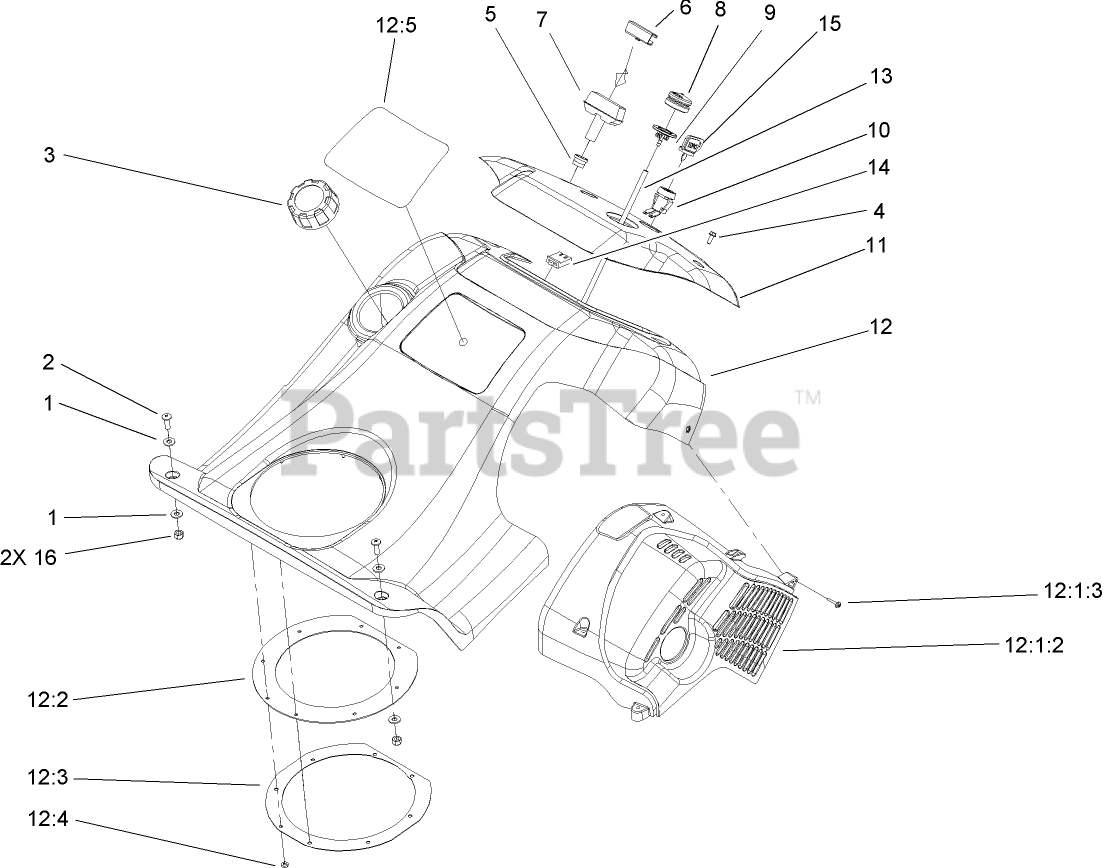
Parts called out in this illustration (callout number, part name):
1	WASHER-FLAT
2	SCREW-PPH
3	GAS CAP ASM
4	SCREW-HWH
5	GUIDE-ROPE, STARTER
6	CLIP-STARTER
8	BULB-PRIMER
9	BODY-PRIMER
10	SWITCH
12:1:2	SHIELD-HEAT
12:1:3	SCREW-PPH
12:2	SEAL-CHUTE
12:3	RETAINER-SEAL, CHUTE
12:4	PALNUT
12:5	DECAL-SHROUD, ELECTRIC START
13	HOSE-PRIMER
14	CONNECTOR-BODY
15	KEY-IGNITION
16	NUT-LOCK, NI
